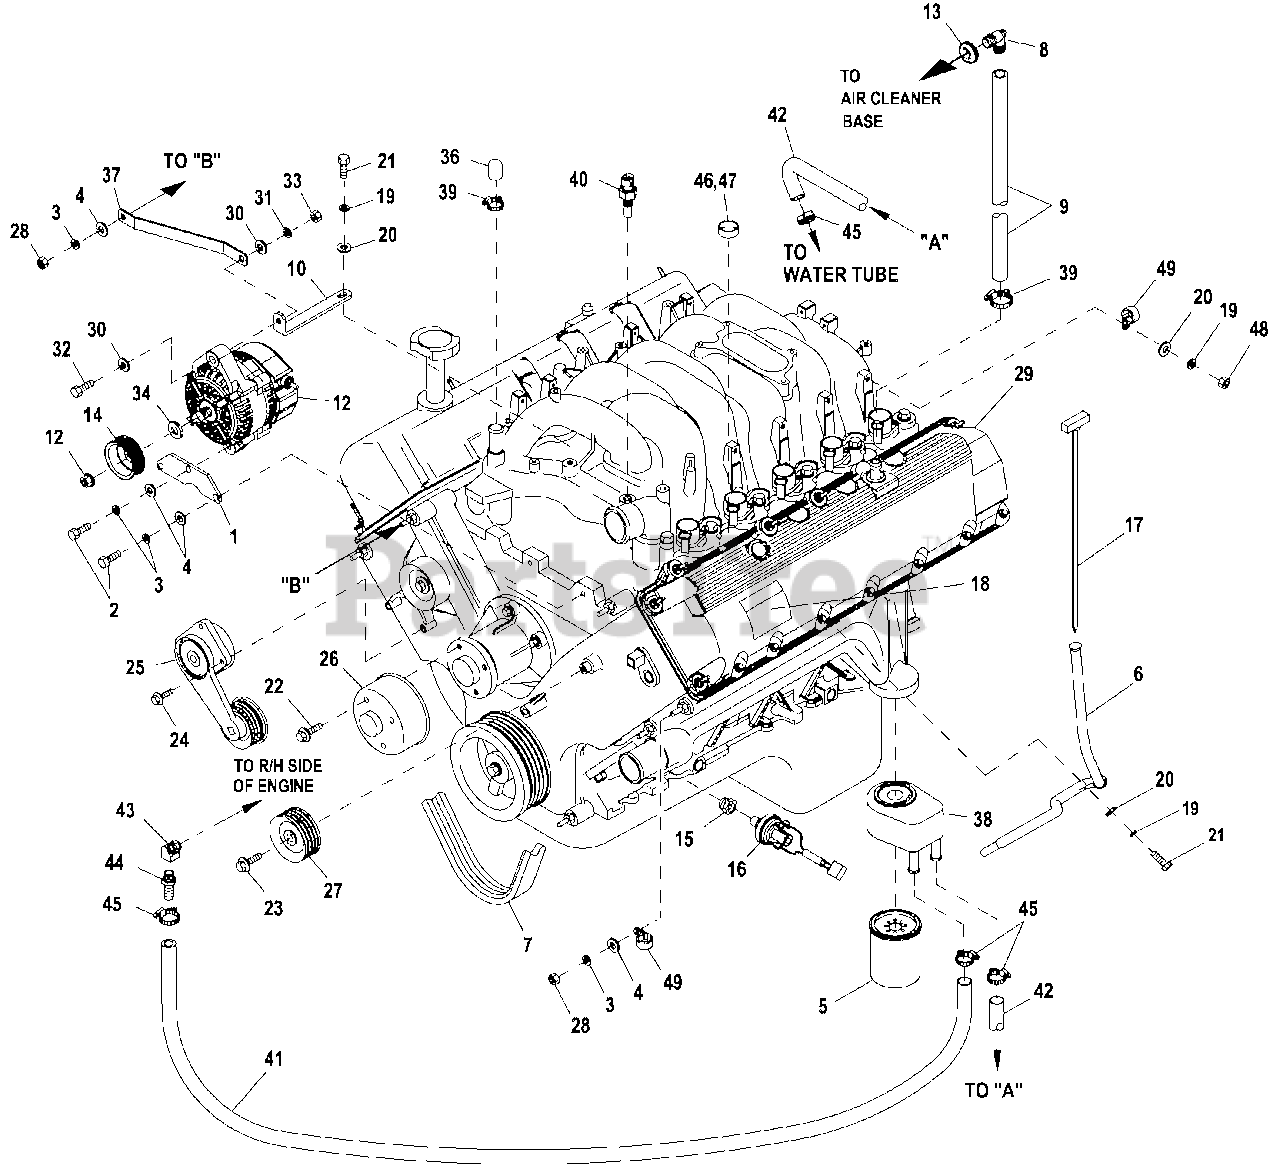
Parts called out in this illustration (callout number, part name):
1	BRACKET,D.C. ALTERNATOR LOWER
2	SCREW HHC M8-1.25 X 20 C8.8
3	WASHER LOCK M8-5/16
4	WASHER FLAT 5/16-M8 ZINC
5	OIL FILTER
6	DIPSTICK TUBE, FORD 6.8L
7	BELT SERPENTINE (65.0" LG) (1800 RPM)
8	BARBED EL 90 5/8 PLASTIC
9	HOSE 3/4 ID SAE-30R2 (16.75"LG)
10	BRACKET DC ALTERNATOR UPPER
12	ALTERNATOR DC W/OUT PULLEY
13	GROMMET .625 X 1.25 X .433
14	PULLEY 80 OD DC ALTERNATOR (1800 RPM)
15	BSHG RDCR HEX 1/4 TO 1/8
16	HARN LOW OIL PRESS SWITCH ASSY
17	DIPSTICK G6.8L G3
18	DECAL LSI EPA CERTIFICATION
19	WASHER LOCK M6-1/4
20	WASHER FLAT 1/4-M6 ZINC
21	SCREW HHC M6-1.0 X 20 G8.8
22	SCREW WP PULLEY M8-1.25 X 19
23	BOLT HEX FL HD M8-1.25 X 28
24	BOLT HEX FL HD M8-1.25 X 31
25	TENSIONER ENG. AUTOMATIC BELT
26	PULLEY WATER PUMP G3 (1800RPM UNITS)
27	PULLEY GROOVED ENGINE IDLER
28	NUT HEX M8-1.25 G8 CLEAR ZINC
29	ENGINE G6.8L G3 V-10 (2009 +)
30	WASHER FLAT 3/8-M10 ZINC
31	WASHER LOCK M10
32	SCREW HHC M10-1.5 X 45 C8.8 FT
33	NUT HEX M10-1.5 G8 YEL CHR
34	SPACER DC ALTERNATOR PULLEY
36	CAP RUBBER
37	BRACKET DC ALT STABILIZER
38	OIL COOLER G3 (150KW 3600RPM)
39	CLAMP HOSE #10 .56-1.06
40	TEMPERATURE SENDER DELPHI
41	HOSE OIL COOLER PREFORMED 3/4 (150KW 3600RPM)
42	HOSE OIL COOLER (150KW 3600RPM)
43	ELBOW 45D STREET 1/2NPT BRASS (150KW 3600RPM)
44	BARBED STR 1/2NPT X 3/4 (150KW 3600RPM)
45	CLAMP HOSE #10 .56-1.06 (150KW 3600RPM)
46	PLUG EXPANSION 14OD
47	ADHESIVE LOCTITE 620
48	SCREW HHC M6-1.0X 1 6 C8.8
49	CLAMP STL/VNL 1.06 X .406 Z
